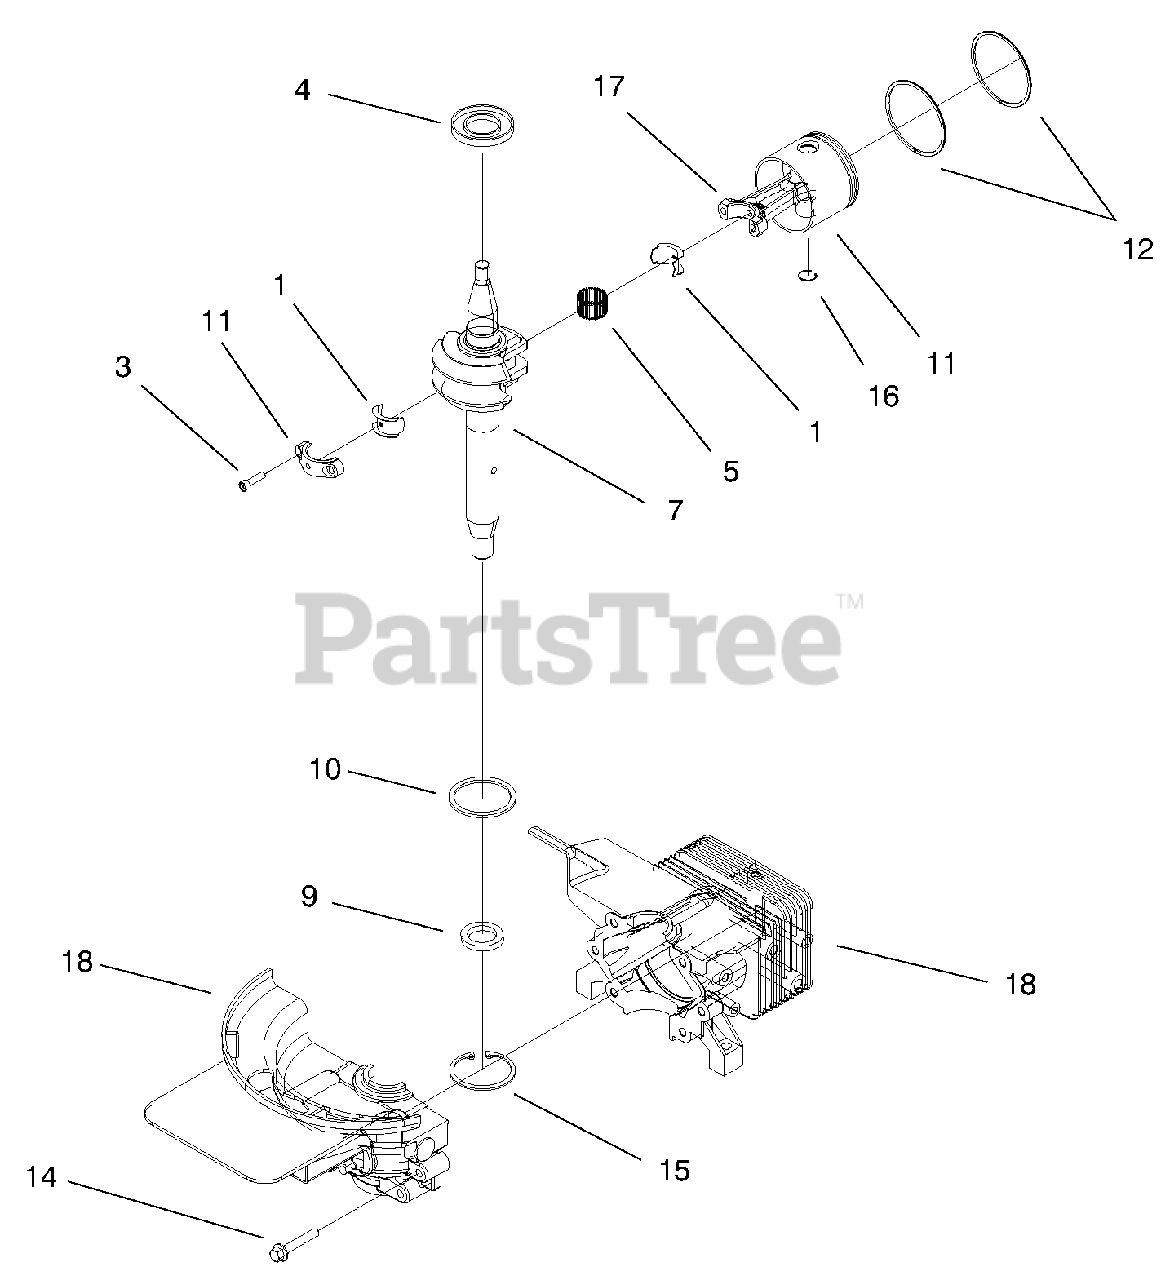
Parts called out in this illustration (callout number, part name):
1	Liner Ay
3	Screw-Rod
4	Seal- Oil
5	Bearing-Needle
7	Crankshaft And Bearing ASM For Service
9	Seal-Oil
10	Ring-Retaining
11	Piston ASM With Piston Rings
12	Ring Set-Service
15	Ring-Retaining
16	Ring-Retaining
17	Connecting Rod ASM
18	Cylinder And Crankcase ASM
